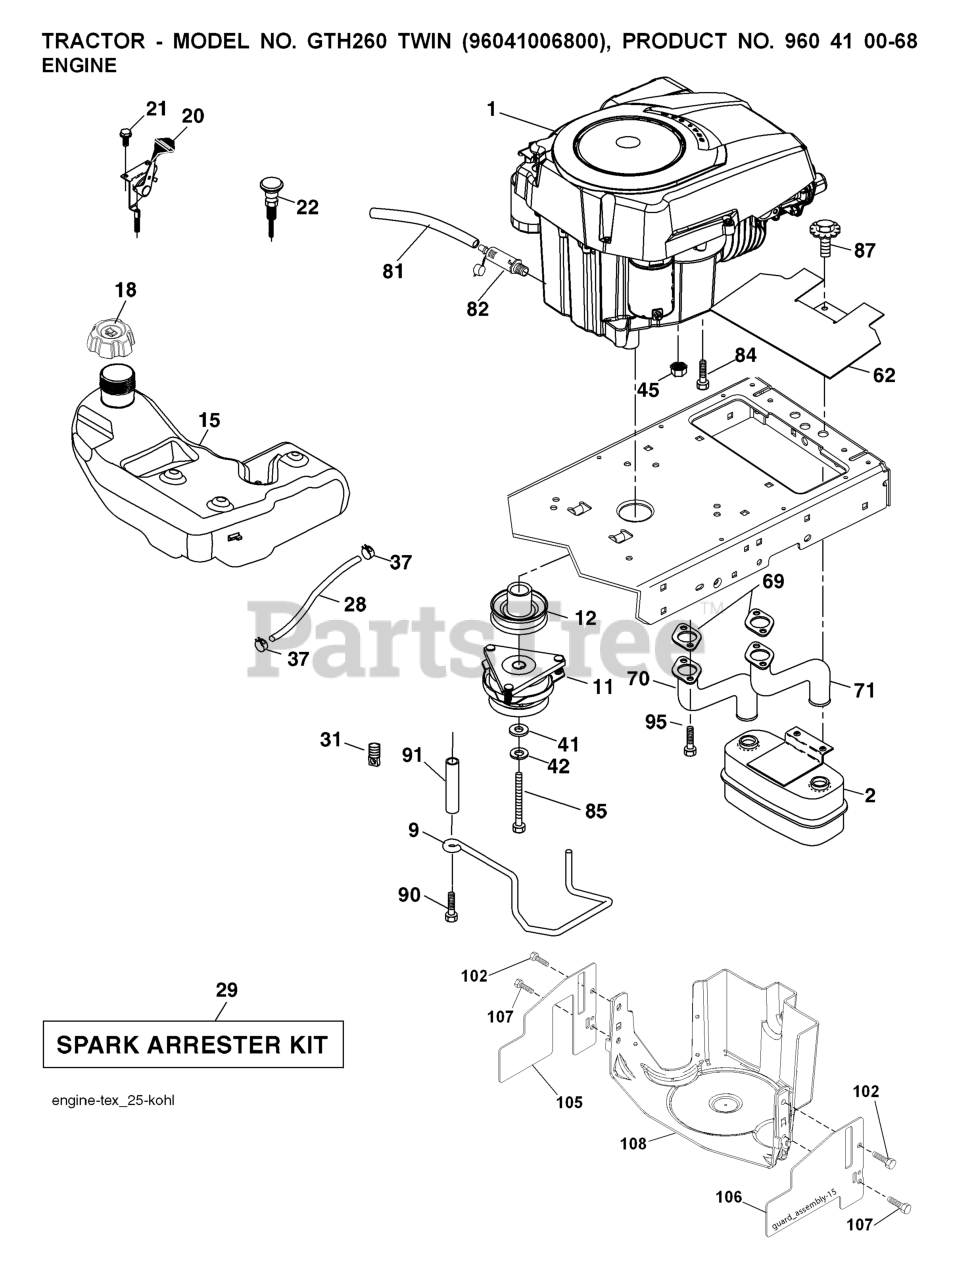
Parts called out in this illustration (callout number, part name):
1	IMPELLER ASSY
2	GEARBOX.ASM.AUGER.D-SHAFT
3	BEARING FLANGE
4	PULLEY.FLANGE.IMPELLER
5	BASE.DISCHARGE.CHUTE
6	BRACKET, CORNER DISCHARGE
7	CLEAN OUT TOOL
8	CLIP.CLEANOUT.TOOL
9	LOCKNUT.NYLOC.1/4-20
10	SCREW.HEX.HD1/4-20X
11	NUTNYLOK.FLRANGE.5/16-18
12	BOLT, HEX HEAD 5/16-18
13	HUB.IMP.PULLEY.D-SHAFT
14	SLEEVE.IMP.PULLEY.D-SHAFT
15	NUT LOCK FLG 3/8-16 UNC
16	BOLT.CARRIAGE.5/16-18X
17	SCREW.HWH.13-16-5.8.BZP
18	CASE PLUG
19	GEAR.BOX.COVER.RIGHT.SIDE
20	GASKET.GEAR.BOX
21	OIL SEAL
22	FLANGE BUSHING-1"
23	WASHER TRUST 1"
24	WORM GEAR
25	AUGER SHAFT
26	KEY, SQUARE 1/4 X .875
27	FLANGE BUSHING-5/8
28	WASHER, THRUST 5/8
29	SHAFT.IMPELLER.D-SHAFT
30	PIN, ROLL 3/16 X 1-1/8
31	WASHER, THRUST 3/4
32	BEARING TRUST 3/4 NTA-1220
33	BUSHING, FLANGE 3/4
35	HEX SCREW-5/16 X 3/4
36	GEAR.BOX.COVER.LEFT.SIDE
37	BOLT.SHOULDER.SHEAR.1/4-20.
